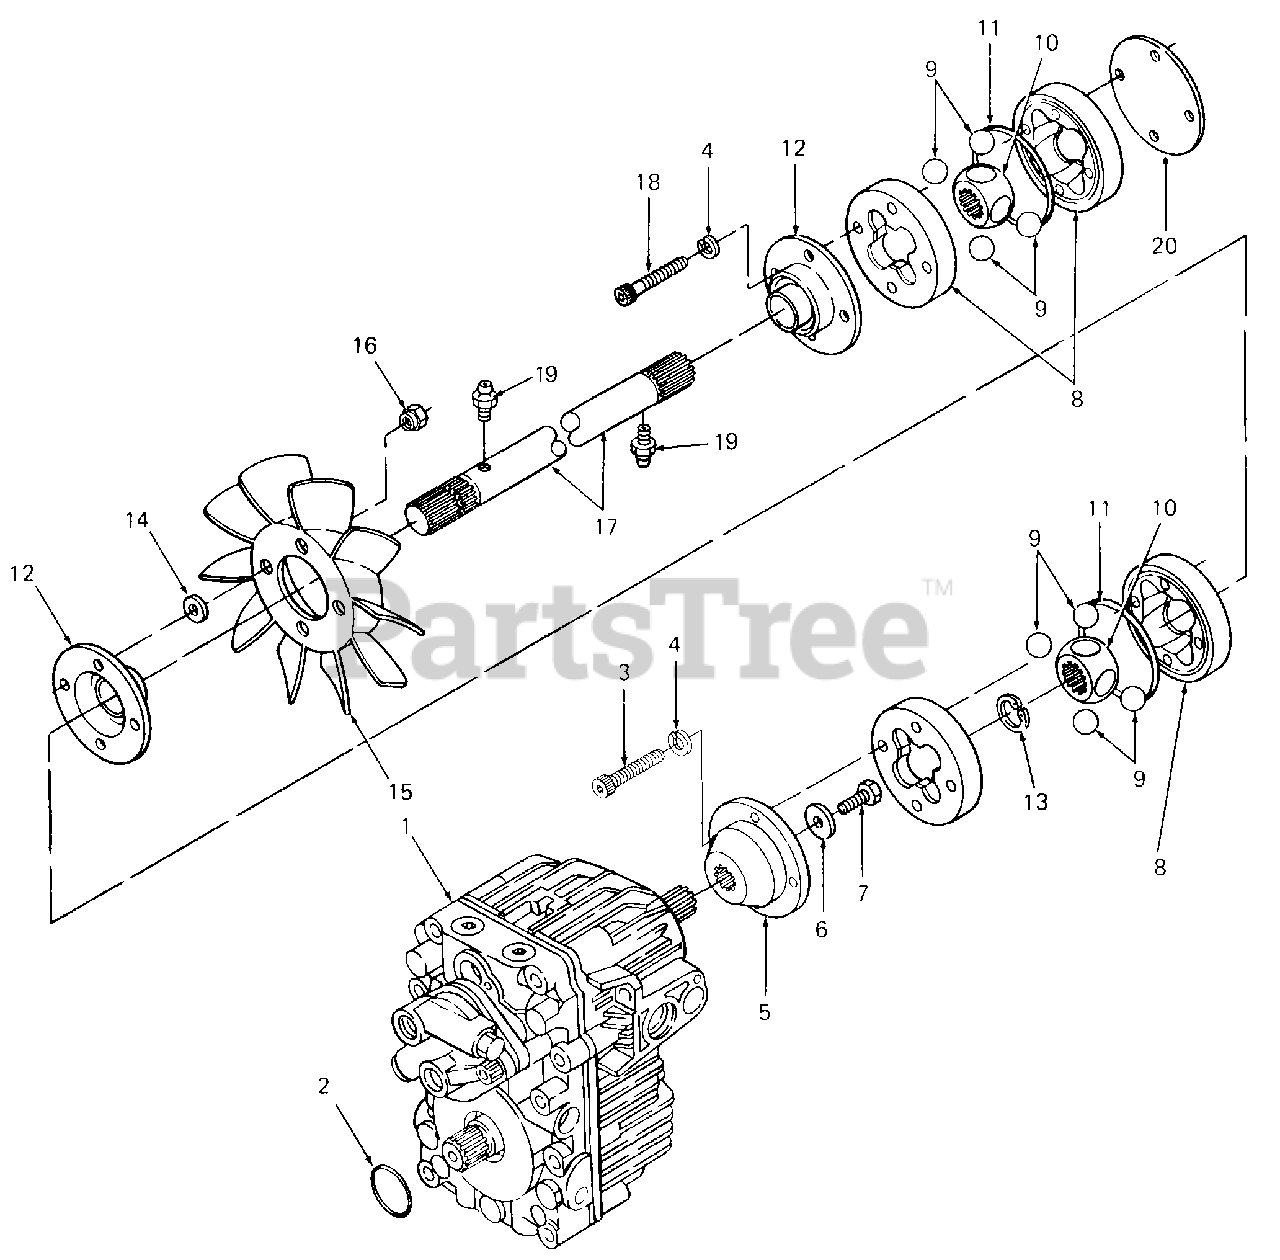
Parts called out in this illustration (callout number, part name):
1	Pump, Hydrostatic
2	O-Ring, 2.75 ID X .103 Dia
3	Screw, Socket Hd Cap, 1/4-20 X 2.0 Lg
4	Washer, Lock, 1/4
5	Adapter, Pump
6	Washer, Bell, .265 X .75 X .062 Thk
7	Bolt, Hex Patch, M6-1.0 X 20 MM Lg GR10.9
8	Coupling, Drive w/O-Ring Groove
9	Ball, Steel, 5/8 Dia Chrome
10	Hub, Drive
11	O-Ring, 2.489 X .070
12	Boot, Coupling
13	Ring, Snap
14	Washer, Flat, .25 X .62 X .052 Thk
15	Fan, 10 Blade Hydro
16	Nut, Fan, 1/4-20
17	Shaft, Drive, 18.0 Lg
18	Screw, Socket Hd Cap, 1/4-20 X 1.75 Lg
19	Fitting, Grease
20	Cover, Coupling
